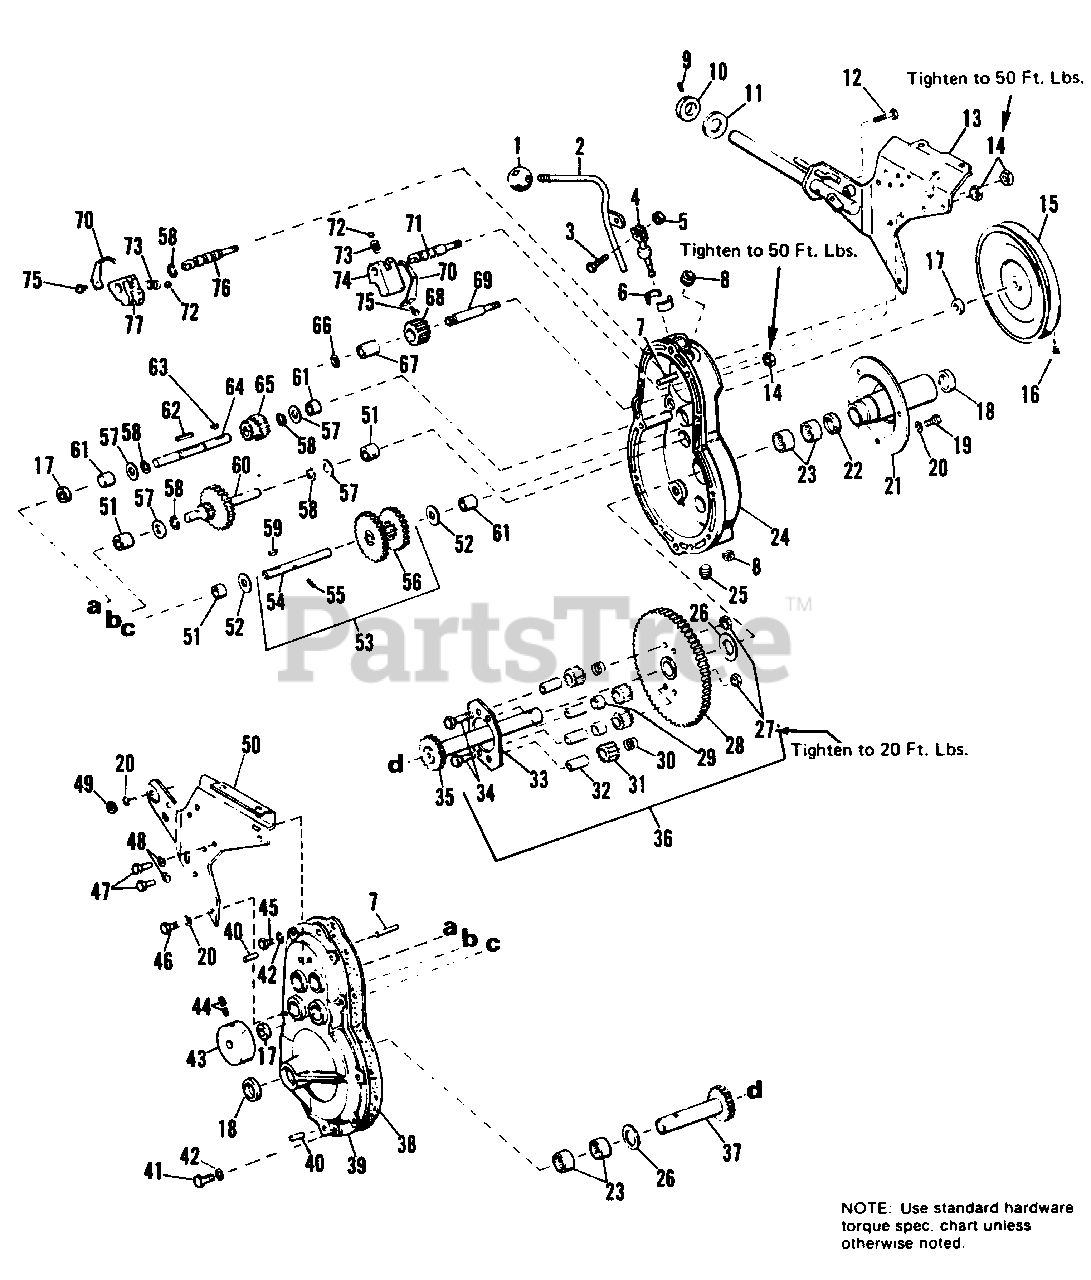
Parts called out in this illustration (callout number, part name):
2	ROD ASSY., Shift
3	CAPSCREW, Hex Hd., 1/4-20 x 3/4
4	ROD ASSY., shift
5	LOCKNUT, Hex, 1/4-20
6	BUSHING, Half
7	PIN ASSY., Roll
9	SETSCREW, 5/16-18 x 1/2
10	COLLAR, Set
11	WASHER, Thrust
12	CAPSCREW, Hex Head, 3/8-16 x 1-3/4
13	PLATE ASSY., Side
14	NUT, Hex, Full, 7/16-14
15	PULLEY, Transmission
16	SETSCREW, 3/8-24 x 3/8
19	CAPSCREW, Hex Hd., 3/8-16 x 7/8
20	LOCKWASHER, 3/8
21	HOUSING ASSY., Axle
23	BEARING, Roller
24	CASE ASSY., Gear (Includes 918113, 156072, 156073, 101042, 156308 & 156031)
25	PLUG, Pipe
27	LOCKNUT, Hex, 3/8-16
28	GEAR ASSY., Drive
29	SPACER, Diff.
31	PINION, Diff.
33	PLATE, Diff.
34	CAPSCREW, Hex Hd., 3/8-16 x 2-/12
35	SHAFT ASSY., Axle, R.H.
36	GEAR ASSY., Drive
37	SHAFT ASSY., Axle
39	COVER ASSY., Gear Case W/Bearings
40	PIN, Roll, 3/8 x 1
41	CAPSCREW, Hex Hd., 5/16-18 x 1-1/2
42	LOCKWASHER, 5/16
43	DRUM, Brake
44	SETSCREW, 5/16-18 x 5/16
45	CAPSCREW, Hex Hd., 5/16-18 x 1-1/4
46	CAPSCREW, Hex Hd., 3/8-16 x 3/4
47	CAPSCREW, Hex Hd., 7/16-14 x 1
48	LOCKWASHER, 7/16
49	NUT, Hex, Full, 3/8-16
50	PLATE, Side, L.H.
50	PLATE, Side, L.H. (990489 & 990577 Only)
51	BEARING, Roller
53	SHAFT & GEAR ASSY.
54	SHAFT, Brake
55	PIN, Dowel
56	GEAR ASSY., Cluster
58	RING, Retaining
59	KEY, Hi-Pro
60	GEAR & SHAFT ASSY.
61	BEARING, Roller
62	KEY (990489 Only)
64	SHAFT Pulley, P.T.O.
64	SHAFT. Pulley, P.T.O. (990489 Only)
65	PINION ASSY., Hi-Lo
67	BEARING, Roller
68	PINION ASSY.
69	SHAFT, Reverse Pinion
70	SPRING (Not used on 990489)
71	SHAFT, Hi-Lo
72	BALL, Shift, Lock
73	SPRING (990489 & 990577 Only)
74	FORK, Shift, Hi-Lo
75	CAPSCREW, Hex Hd., 5/16-18 x 5/16
76	SHAFT, Shift, Reverse-Lo
76	SHAFT, Shift, Reverse-Lo (990489 Only)
77	FORK, Shift, Reverse
